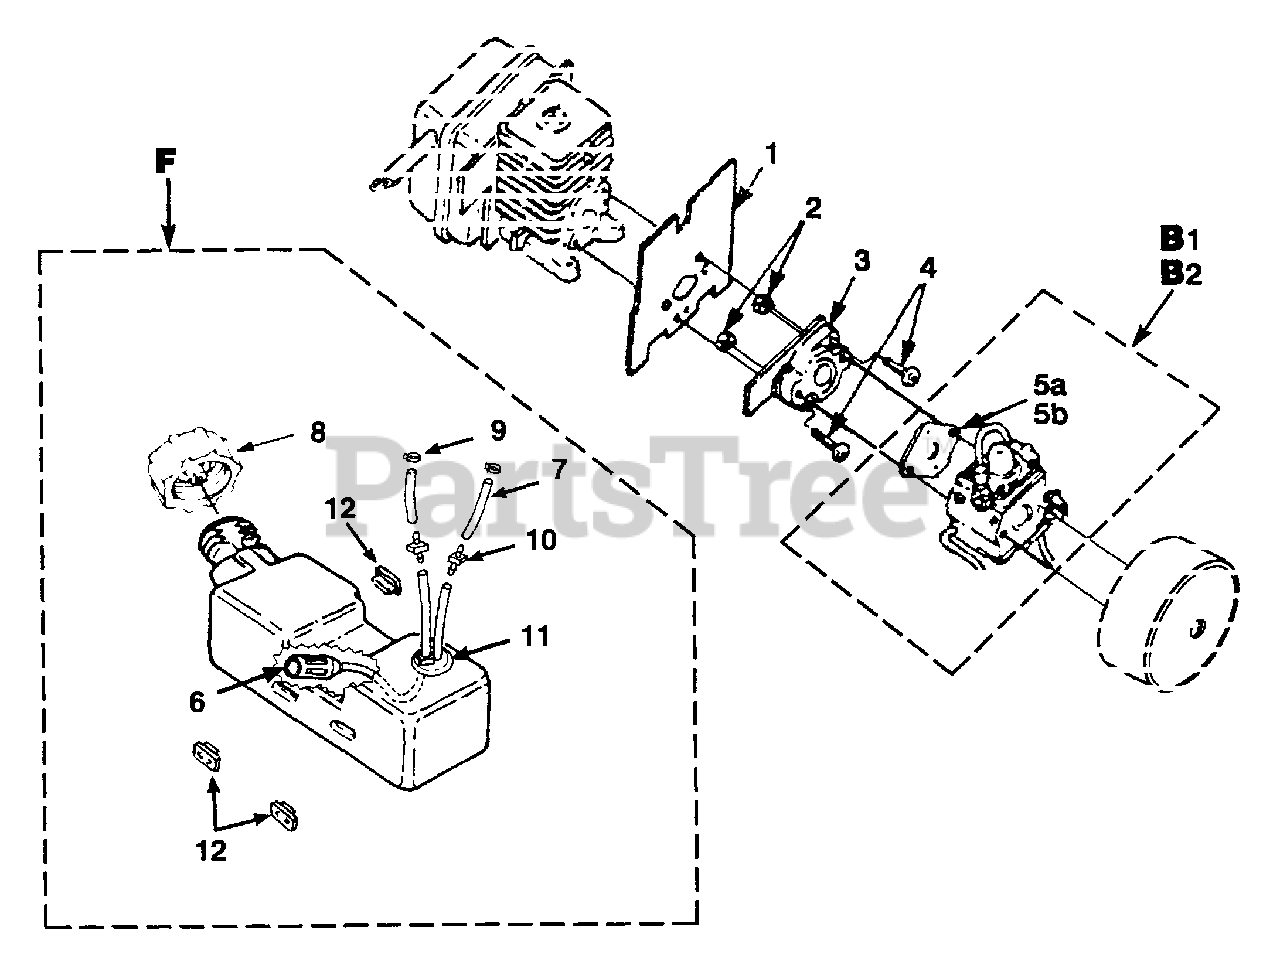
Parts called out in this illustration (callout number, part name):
1	Heat Dam Gasket
2	Hex Nut (1/4-20)
3	Heat Dam
4	Screw, Machine (10-24 x 1 1/8")
5A	Carburetor Gasket
5B	Carburetor Gasket
6	FILTER-Fuel
7	TUBING-Rubber
8	FUEL CAP
10	FITTING - Inlet
11	GROMMET W/Fuel Line
12	BUMPER-Rubber
B1	Carburetor Kit
B2	Carburetor Kit
F	FUEL TANK
